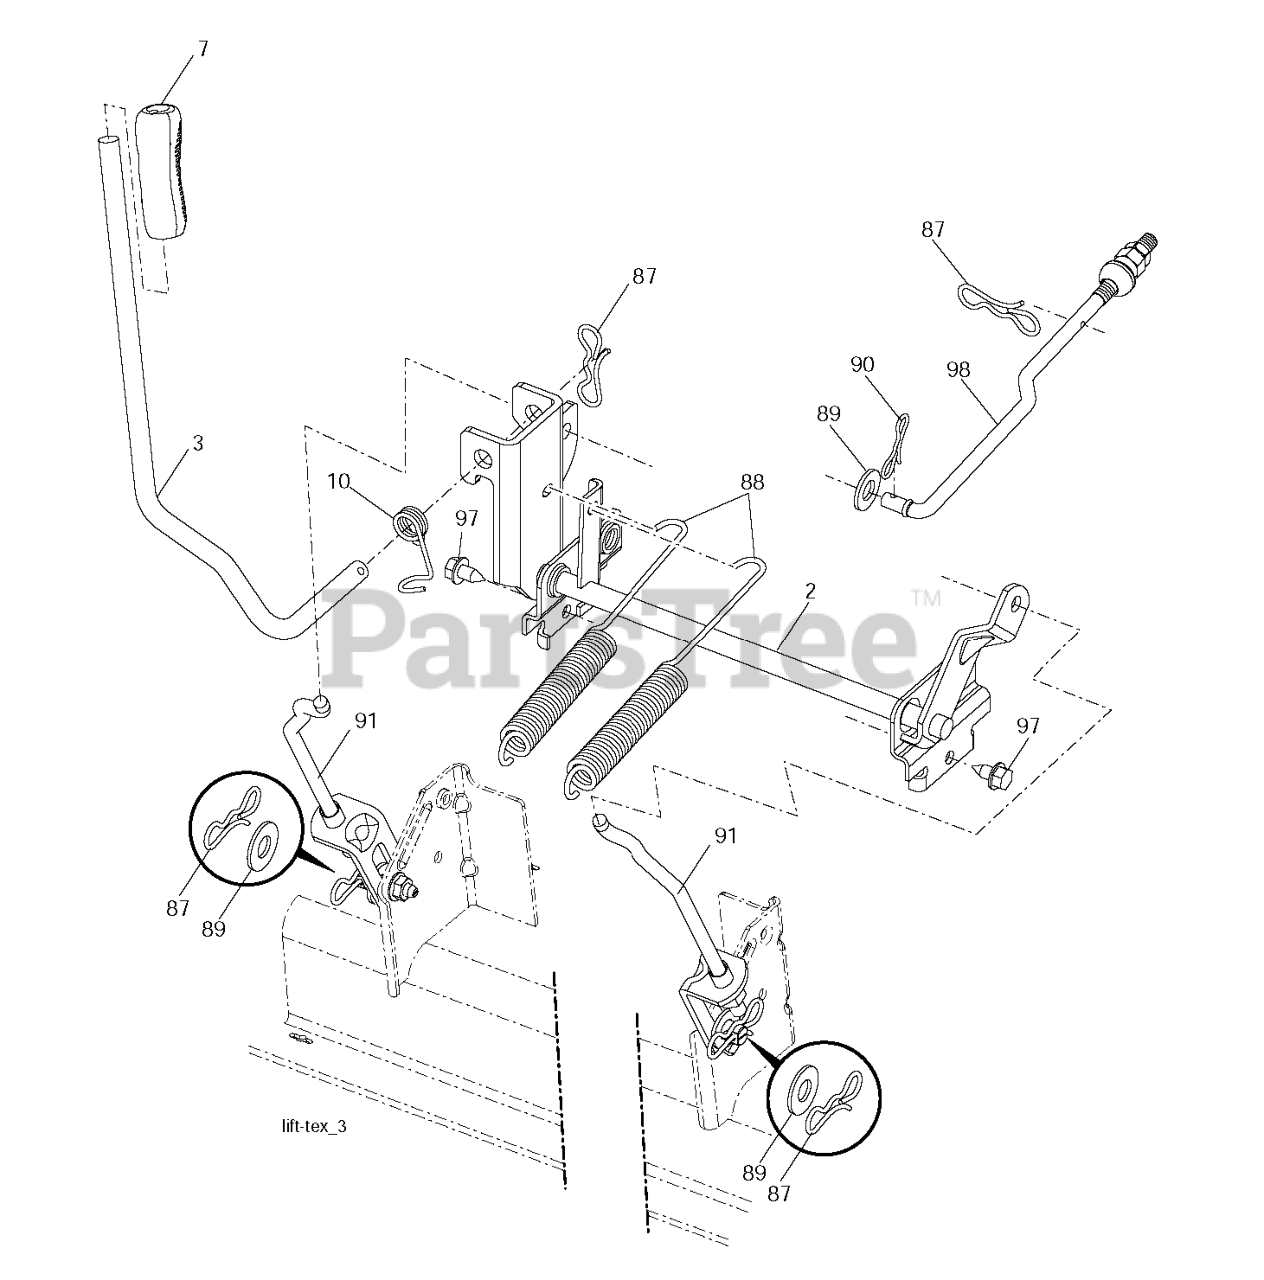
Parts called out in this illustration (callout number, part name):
2	SHAFT.ASM.LIFT.CROSS.H
3	LEVER.LIFT.HANDLE.GT
7	GRIP.HANDLE.LIFT.PVC.BLACK
10	SPRING.TORSION.LIFT.HANDLE
87	PIN.COTTER.7/16.BOW TI.
88	SPRING.LIFT.ASSIST.GT2
89	WASHER.CLEAR.ZINC
90	PIN.COTTER.5/16.BOW TI
91	LINK.ASM.LIFT.54"TG
97	SCREW, 3/8-16X3/4
98	LINK.ASM.SUSP.FRONT.MWR.10.5
